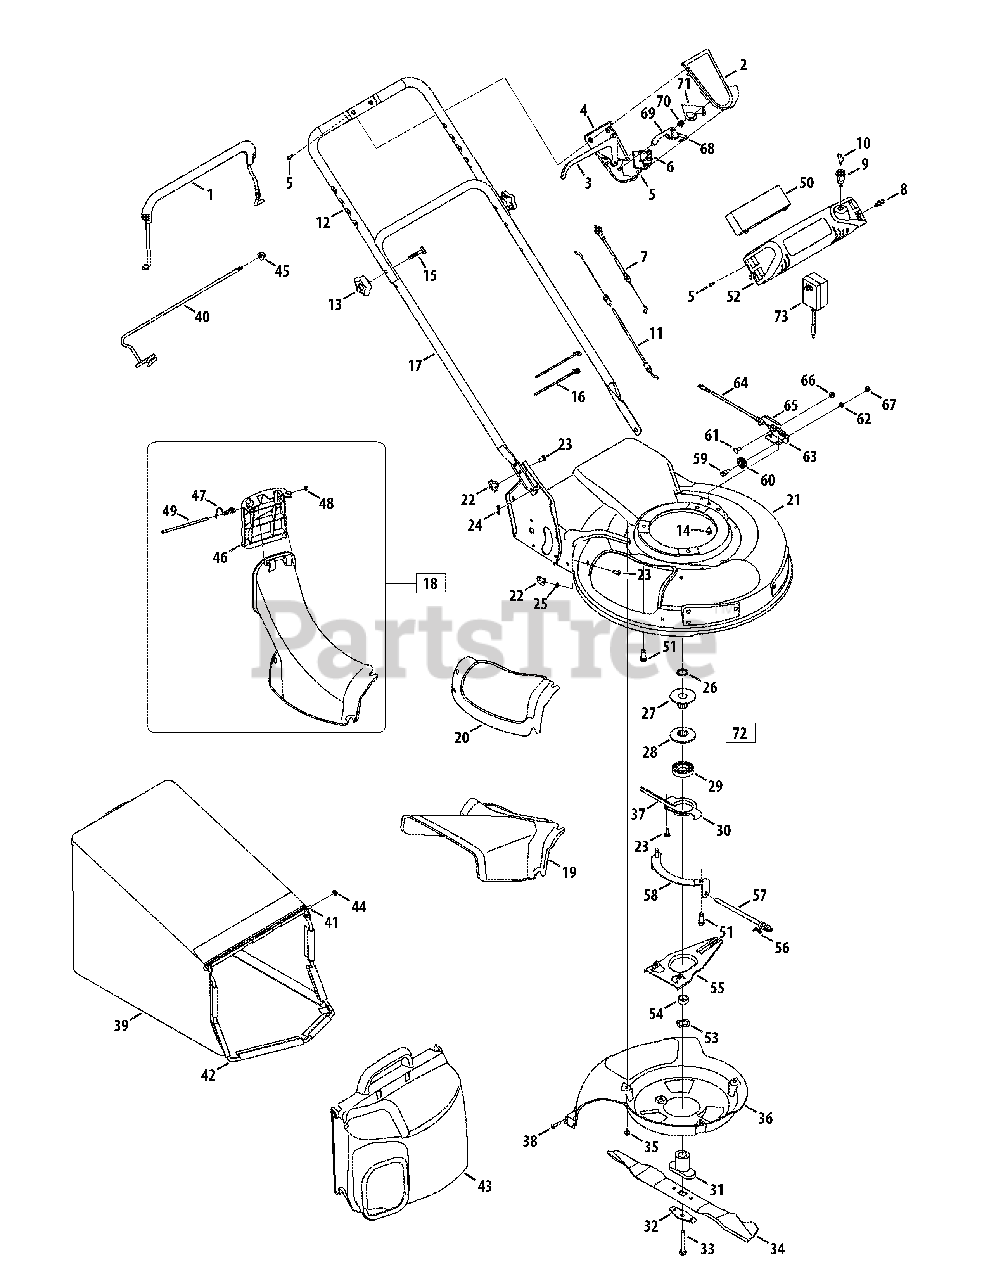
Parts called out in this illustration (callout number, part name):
1	Blade Control
2	Upper Control Housing
3	Drive Control
4	Lower Control Housing
5	C Sunk Tap Screw, #10 x.75 Lg
6	Cable Mounting Cap
7	Drive Cable
8	Rivet
9	Key Switch
11	Control Cable
12	Upper Handle
13	Star Knob
14	Screw, 1/4-20 x .625
15	Carriage Bolt, 5/16-18 x 2.0
16	Cable Tie
18	Adapter Assembly
19	Side Discharge Chute
20	Mulch Cover
22	Wing Nut
23	Carriage Bolt, 1/4-20 x .75"
24	Cotter Pin
25	Push Nut, .25 x ID x .50 OD
26	Sleeve Spacer, .88ID x 1.13OD
27	Half Pulley: 2.62 OD
28	Half Pulley: 2.62 OD x 1.61
29	Ball Bearing
31	Blade Adapter
32	Blade Bell Support
33	Hex Bolt, 3/8-24 x 2.5
34	21" Mulching Blade
35	Screw, 1/4-20 x 3.75
36	Baffle
37	Belt, 3/8 x 39.24
38	Screw, 1/4-15 x .750
39	Grass Catcher
40	Support Rod w/ Rope Guide
41	Pivot Rod
42	Grass Catcher Frame
43	Grass Catcher Cover
44	Cap Nut
45	Flange Lock Nut, 5/16-18
46	Chute Door
47	Torsion Spring
48	Push Cap
49	Pivot Rod
50	12V Battery
51	Sems Screw, 3/8-16 x 1.00
52	Harness Assembly
53	Wave Washer, 1.38 ID x.88 OD
54	Slve Spacer, .88 ID x 1.00 OD
57	Pivot Shaft
59	Shlder Screw, .375 ID x 1/4-14
60	Cable Roller
61	Carriage Screw, 1/4-20 x .62
62	Lock Washer, 1/4
63	Cable Mounting Bracket
64	6 Speed Cable
65	Cable Adjustment Bracket
66	Hex Nut 1/4-20
67	Hex Nut 1/4-28
68	Shift Lever Spring
69	6 Speed Shift Lever
70	Gear Insert
71	6 Spd. Rack Cable Bracket
72	Pulley Assembly
73	12V Battery Charger
